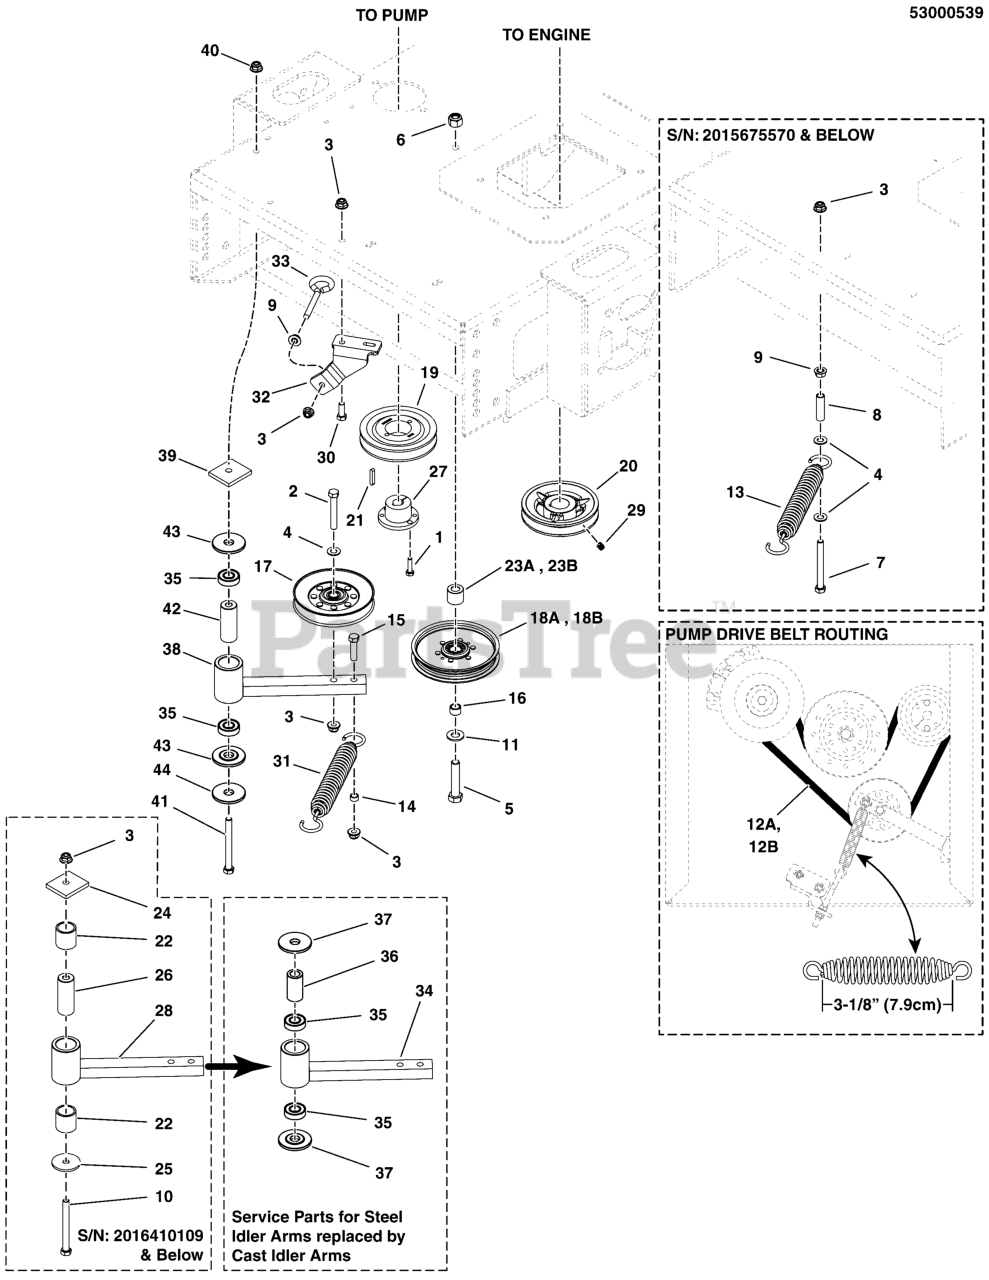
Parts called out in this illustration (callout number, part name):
1	BOLT, 1/4-20 X 1" GD5 CZ
2	BOLT, 3/8-16 X 2-1/2" GD5 CZ
3	NUT, 3/8-16 HEX NYLOCK FLANGE
4	WASHER, 3/8 SAE
5	BOLT, 1/2-20 X 2-1/2" GD5 CZ
6	NUT, Hex, Nylon Lock, 1/2-20
7	BOLT, 3/8-16 X 3-1/2" GD5 CZ
8	HOSE, PUSH LOCK 3/8 X 1 3/4
9	NUT, 3/8-16 HEX SERRATED FLANGE
10	BOLT, 3/8-16 X 4" GD5 CZ
11	WASHER, 1/2 SAE
13	SPRING, EXTENSION, SWIVEL, SHORT HOOK
14	SPACER, .38 X .50 X .27
15	BOLT, 3/8-16 X 1-1/2" GD5 CZ
16	INSERT, BEARING
17	PULLEY, IDLER V NOTCH, 5 AB1303
19	PULLEY , 4.75 OD, SINGLE GROOVE BH-48
20	PULLEY, 4.75 OD X 1-1/8 BORE, BC-48
21	KEY, 5MM SQ. W/RADIUS
22	BUSHING, BRASS, 1.25X1X1.25
24	SPACER, IDLER PIVOT
25	WASHER, .41 X 1.75 X .14
26	SPACER, .39 X 1.00 X 2.55, SS
27	BUSHING, 17MM, HQ
28	WELD, ARM, PUMP DRIVE IDLER - BLK
29	SET SCREW, 5/16-18 X 3/8, KNURL, W/PATCH
30	BOLT, 3/8-16 X 1" GD5 CZ
31	SPRING-EXT, .930 ODX4.020LGX.120WR
32	BRACKET, HYDRO SPRING ANCHOR
33	EYE BOLT, 3/8-16 X 5, 2.88THRD, 1EYE, CZ
34	ASSM, IDLER ARM, PUMP DRIVE, 3/8, CAST (SV)
35	BEARING, BALL, AXLE
36	SPACER, .39 X .88 X 1.53, CZ
37	SPACER, IDLER ARM, T-STYLE, CZ
38	ASSM, IDLER ARM, PUMP DRIVE, 1/2, CAST (SV)
39	SPACER, .52ID X 2 X 1.75RCT X .25, CZ
40	NUT, Hex Flange, Nylock, 1/2-13
41	BOLT, 1/2-13 X 4" GD5 CZ
42	SPACER, .52 X .84 X 1.53, PM
43	SPACER, IDLER ARM, 1/2, PM
44	WASHER, .52 X 1.75 X .14, CZ
